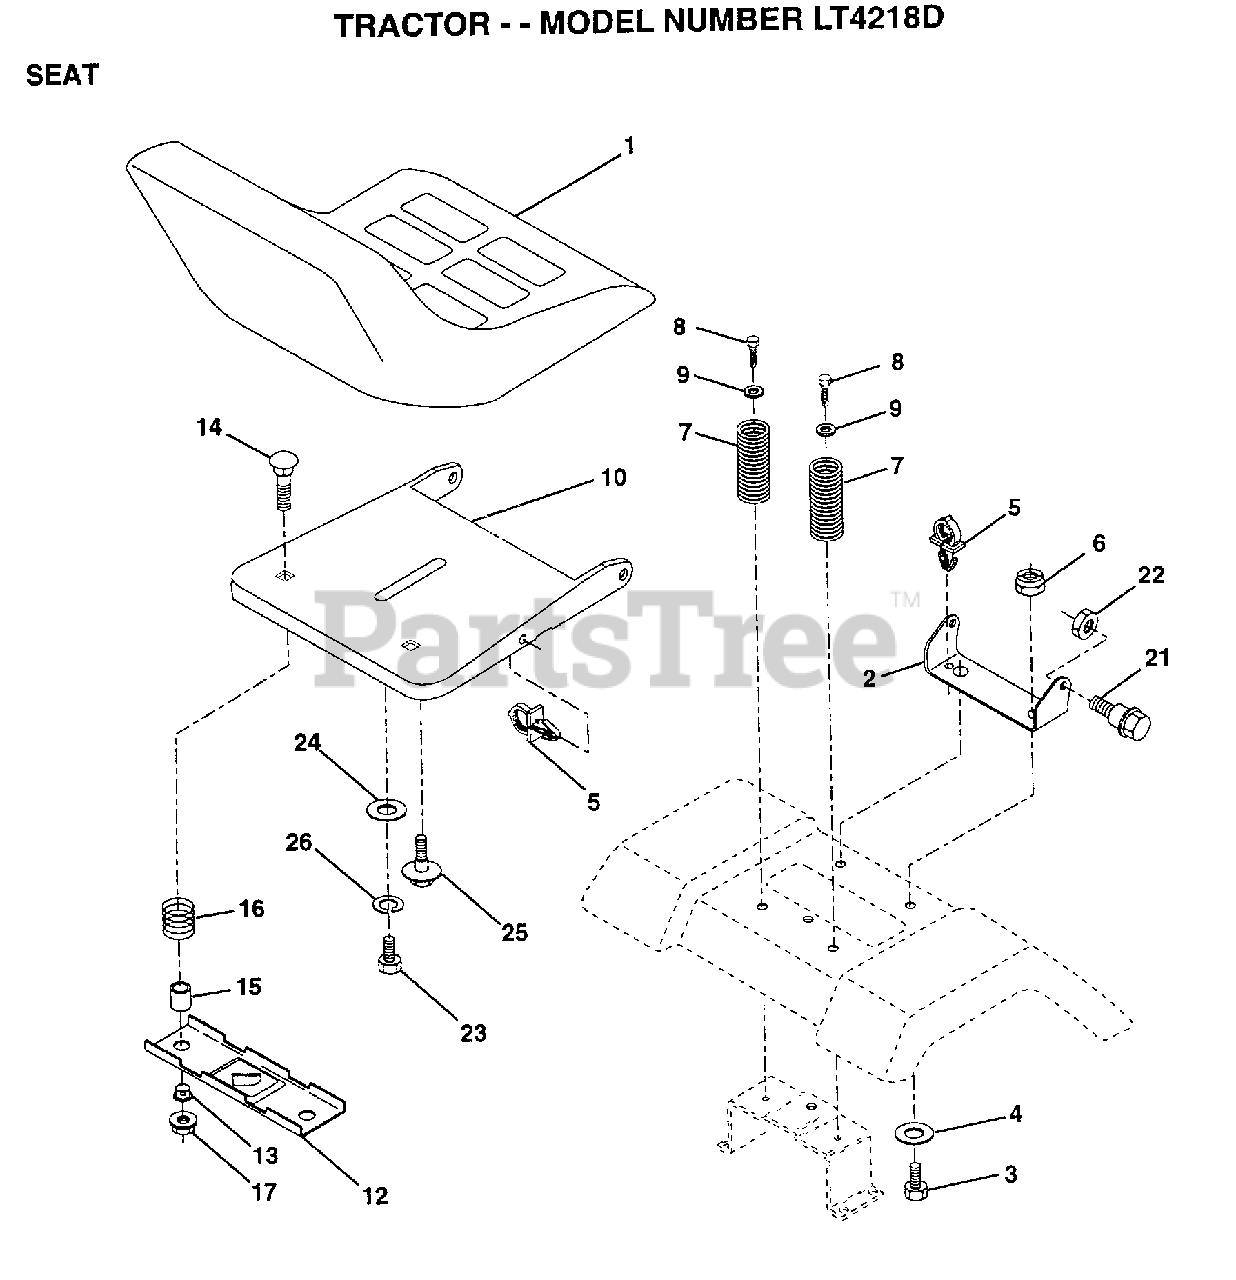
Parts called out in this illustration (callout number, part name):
1	SEAT.2400/1416.BK
2	BRACKET PVT SEAT
3	BOLT
4	WASHER PM
5	CLIP.PUSH-IN.HING
6	NUT
7	SPRING COMPRESSIO
8	SCREW GTV
9	WASHER
12	BRKT SWITCH
13	BUSHING
15	SPLIT SPACER
16	SPRING
21	"BOLT,SHOULDER"
22	NUT
23	BOLT
24	WASHER
25	"BOLT,SHOULDER"
26	LOCKWASHER
